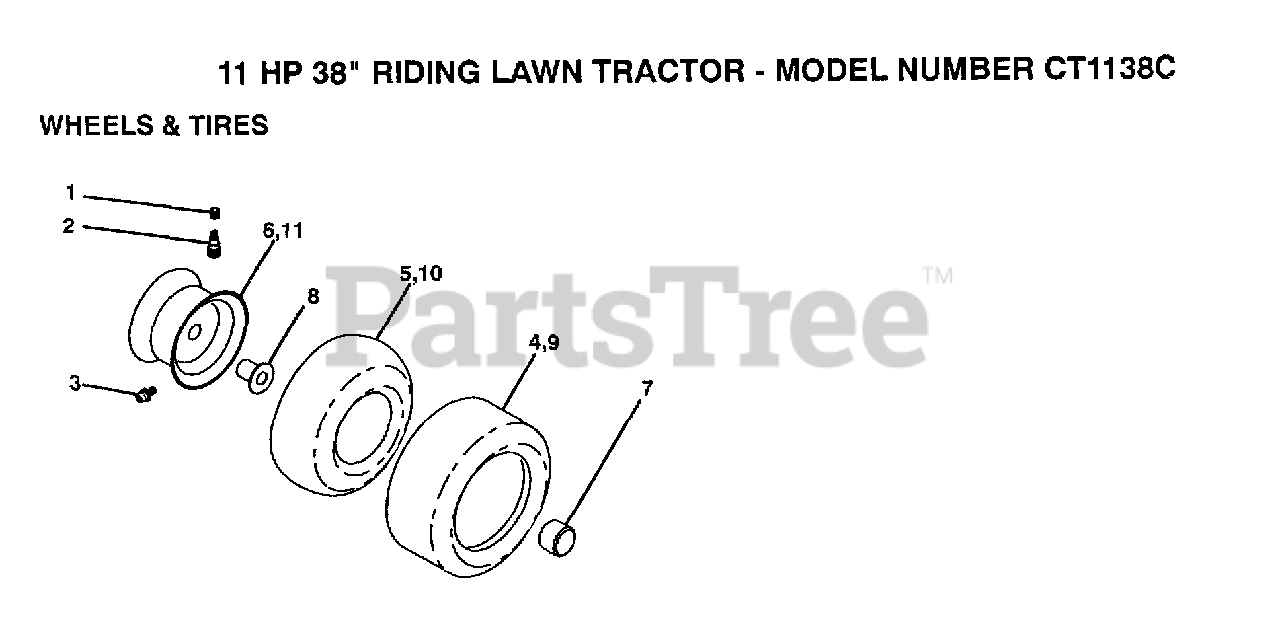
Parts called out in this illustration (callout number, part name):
1	VALVE CAP
2	VALVE STEM LT
3	FITTING LT
5	TUBE.5.3/4.5/6
7	HUB CAP
8	"FLANGE, BEARING"
10	TUBE.18X9.5-8
